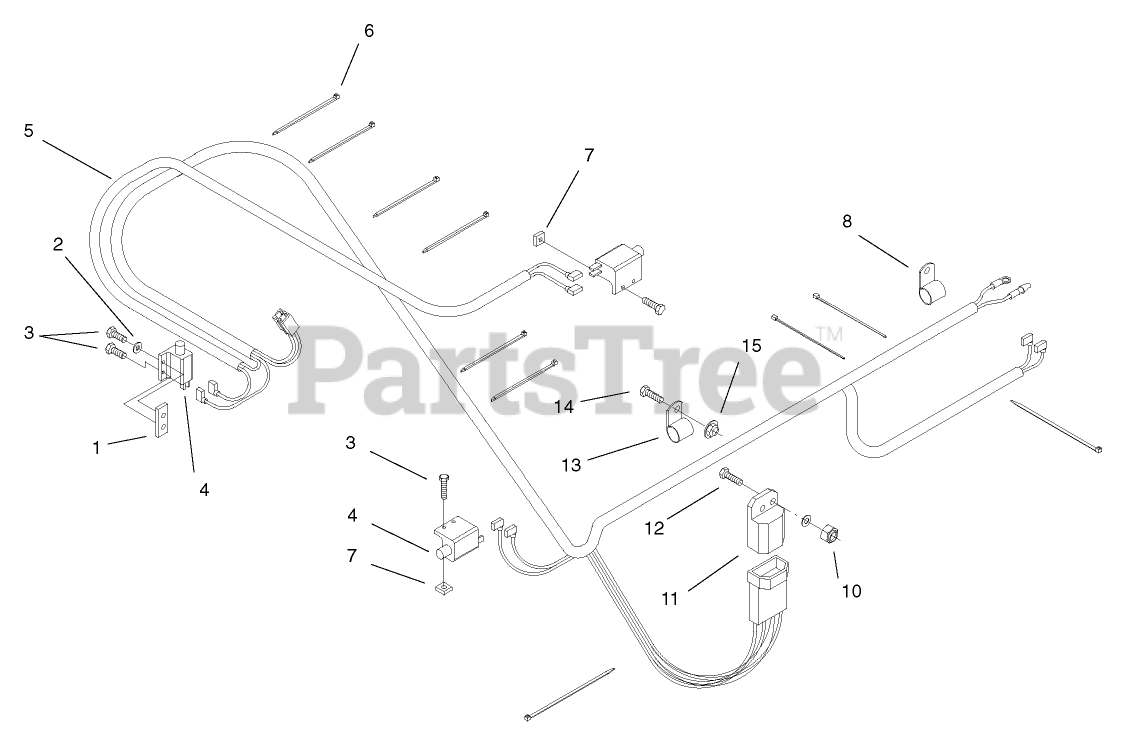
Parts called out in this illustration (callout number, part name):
1	PLATE-TAPPED
2	WASHER-FLAT
3	SCREW-PPH
4	SWITCH-OPEN, NORMALLY
5	Harness-Wiring
6	TIE-CABLE
7	Nut-SQH
8	Clip-Loom
10	NUT-LOCK, NI
11	MODULE-INTERLOCK
12	SCREW-HH
13	CLIP-LOOM
14	SCREW-HH
15	NUT-HF
16	SCREW-HH
